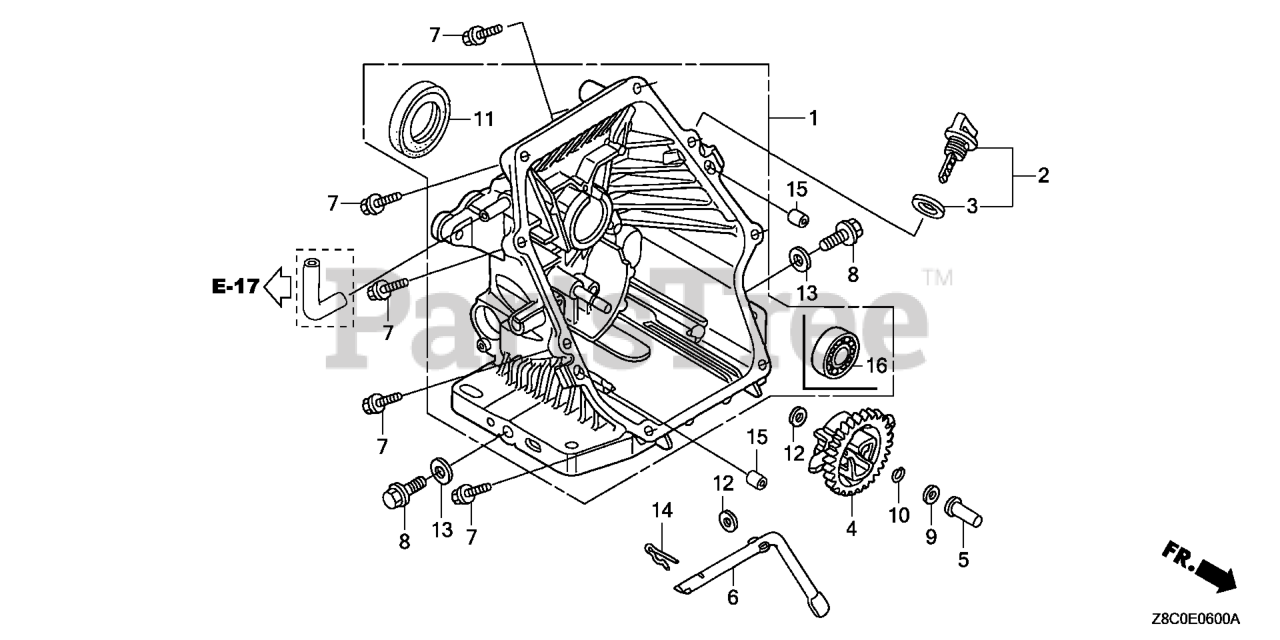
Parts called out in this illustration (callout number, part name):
1	COVER ASSY., CRANKCASE
2	GAUGE ASSY., OIL LEVEL
3	GASKET, OIL FILLER CAP (NOT AVAILABLE)
4	GOVERNOR ASSY.
5	SLIDER, GOVERNOR
6	SHAFT, GOVERNOR ARM
7	BOLT, FLANGE (6X25) Use up to Engine SN 2056819.
8	BOLT, DRAIN PLUG
9	WASHER, THRUST (6MM)
10	CLIP, GOVERNOR HOLDER
11	OIL SEAL (28X41.25X6)
12	WASHER, PLAIN (6MM)
13	WASHER, DRAIN PLUG (12MM)
14	PIN, LOCK (8MM)
15	PIN, DOWEL (8X20)
